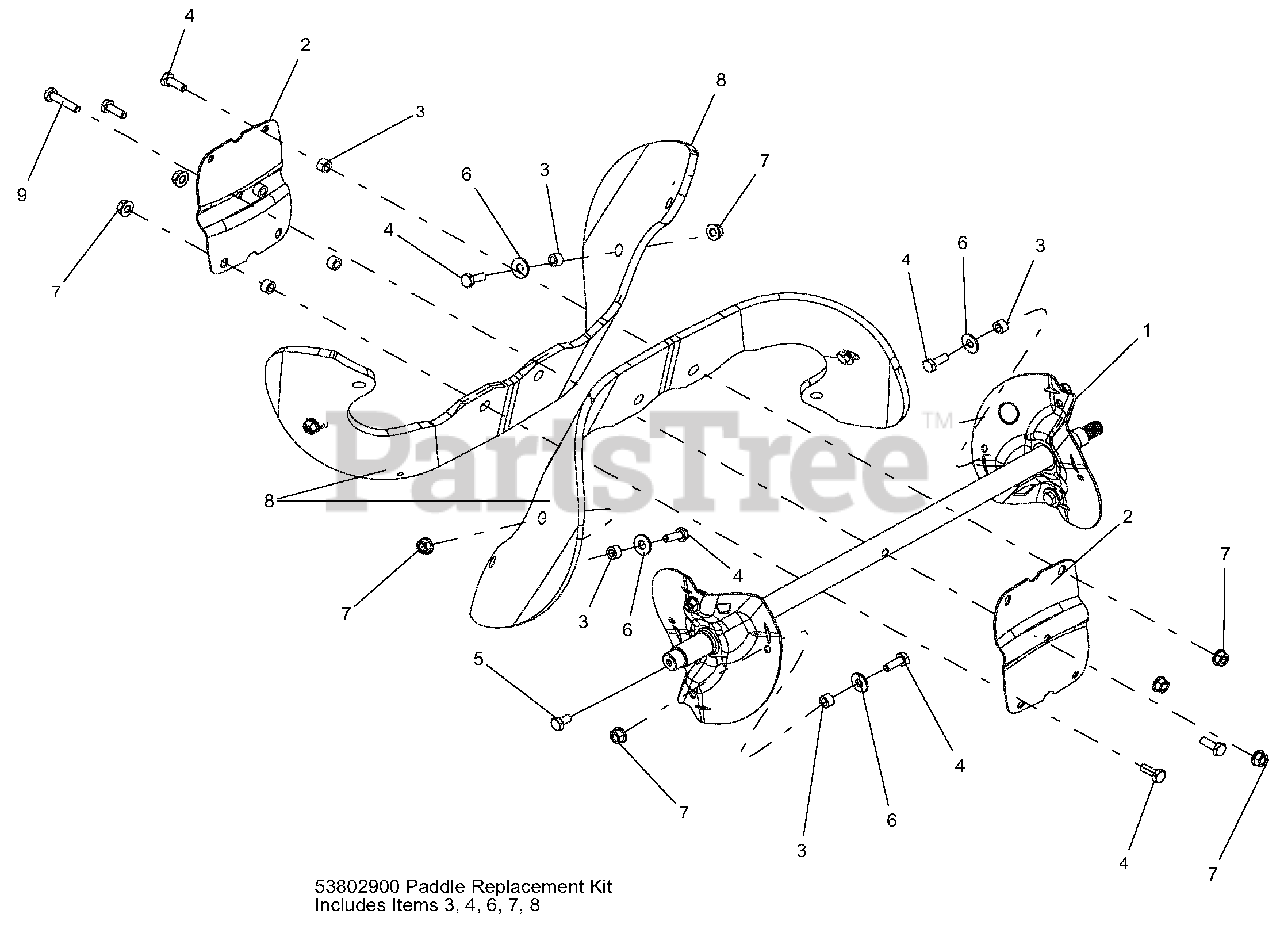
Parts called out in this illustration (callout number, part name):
1	ASSEMBLY, AUGER FRAME
2	PLATE, CENTER AUGER
3	BUSHING, .26 ID X .44 OD X .26
4	@BLT-HEX .25-20X.75 GR5 YWZC
5	@BLT-HEX .25-20X.50 GR5 YWZC
6	@WSHR-FL-STL.312X.734X.065 YWZ
7	@NUT-LK-TOP-FLG .25-20 YWZC
8	KIT, PADDLE REPLACEMENT
9	@BLT-HEX .25-20X1.25 GR5 YWZC
